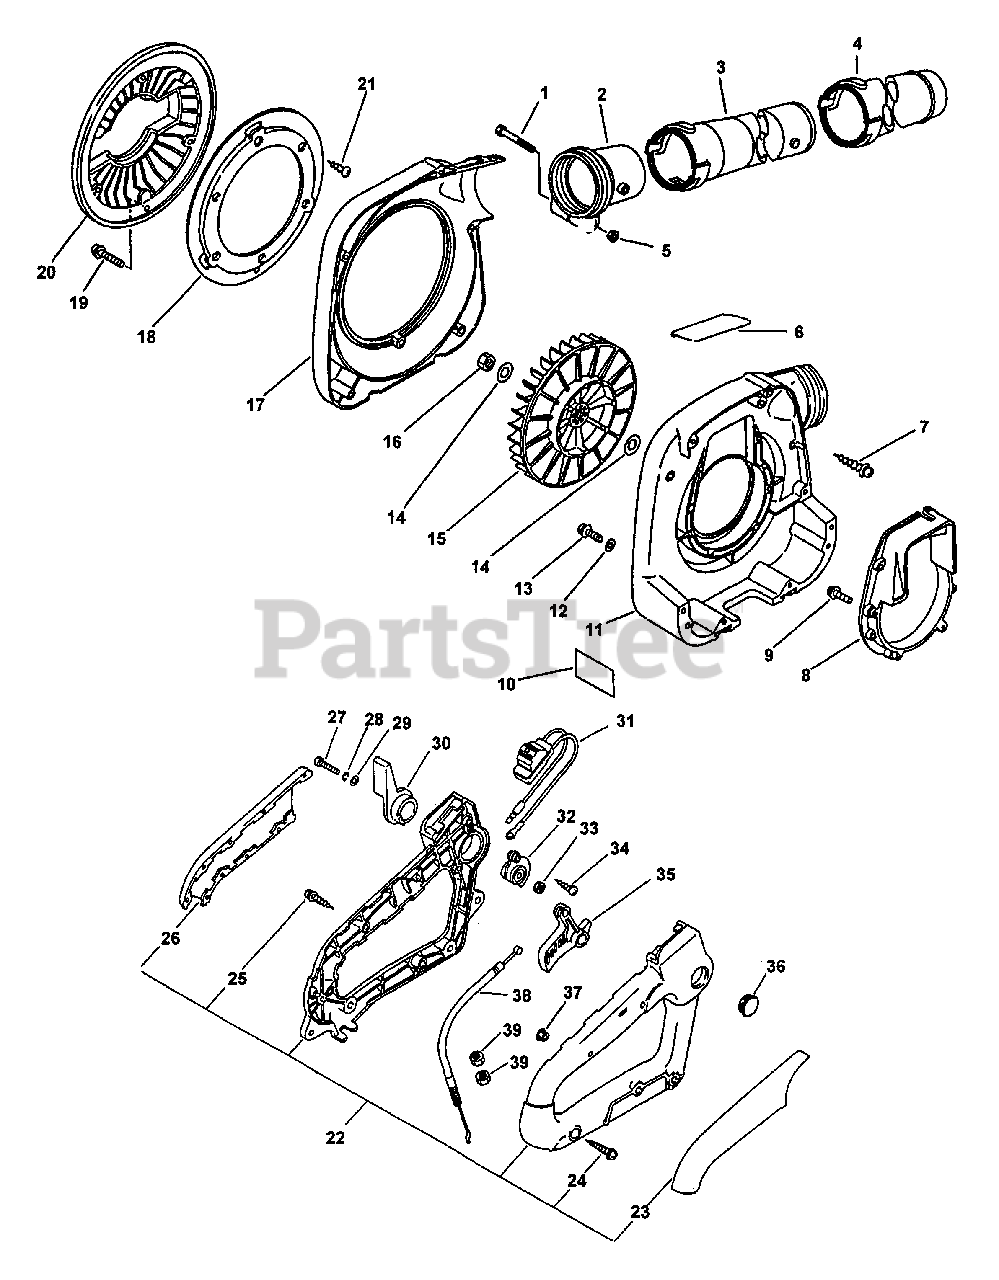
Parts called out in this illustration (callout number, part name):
1	SCREW - 5×60
2	ADAPTER, TUBE
3	TUBE, BLOWER - STRAIGHT
4	TUBE, BLOWER - NOZZLE
5	NUT, FLANGE M5
6	LABEL - NOISE
7	SCREW 5×30
8	BRACKET, ENGINE
9	SCREW 4×18
10	LABEL - CAUTION
11	CASE, FAN
13	SCREW 4×22
15	FAN
17	COVER, FAN - LEFT
18	BASE, GRID
19	SCREW 5×16
20	SHIELD, DEBRIS
21	SCREW 4×10
22	HANDLE KIT
23	GRIP, RIGHT
24	SCREW 5×35
25	SCREW 4×22
26	GRIP, LEFT
27	SCREW 6×20
28	WASHER, SPRING 5
29	WASHER 6.5×13×1
30	CONTROL, THROTTLE
31	IGNITION SWITCH ASSY
32	BRACKET, THROTTLE
33	NUT, HEX M6
34	SCREW 4×10
35	TRIGGER, THROTTLE
37	NUT, FLANGE M5
38	CABLE, THROTTLE
